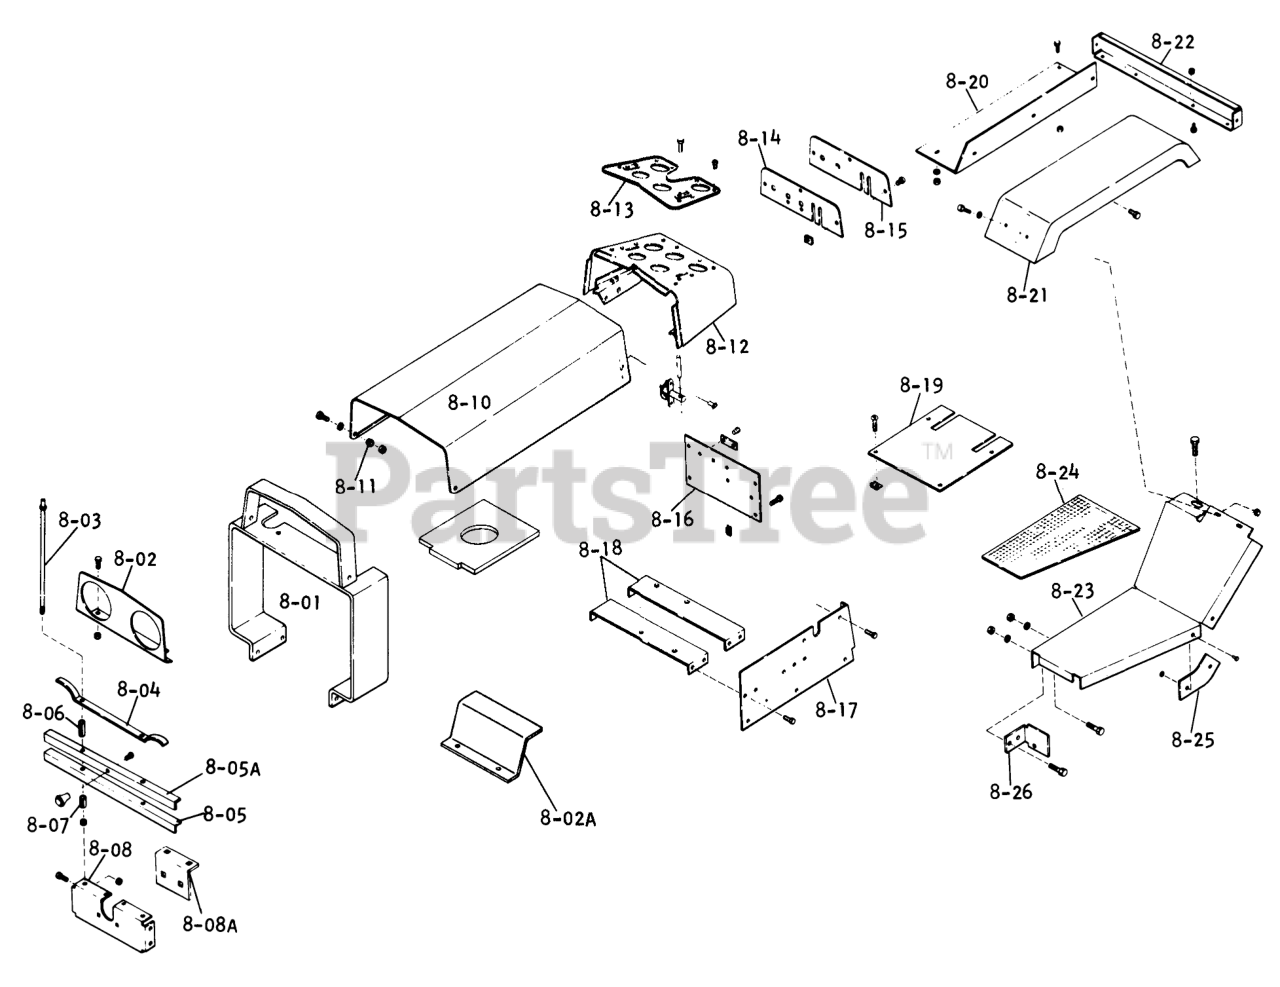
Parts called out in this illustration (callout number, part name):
8-01	Asy-Grille Shroud
8-02	Light Bracket
8-02A	Cotter Pin
8-03	ROD-GRILLE
8-04	SPRING GRILLE
8-05	Grille
8-05A	Angle-Grille
8-06	Spacer
8-07	Spacer
8-08	Cover-Front
8-08A	Cover
8-10	Hood Assembly
8-11	Bushing
8-12	Control Housing
8-13	Right Differential Gear
8-14	Idler Shaft
8-15	Plate-Instrument Instruction
8-16	Panel
8-17	Panel-Console RH
8-18	Battery Support
8-19	Access Cover Plate
8-20	Plate-Fender RH
8-21	Fender-Right and Left
8-22	Channel
8-23	Footrest RH
8-24	Footrest Mat RH
8-25	Filler Plate
8-26	Bracket
